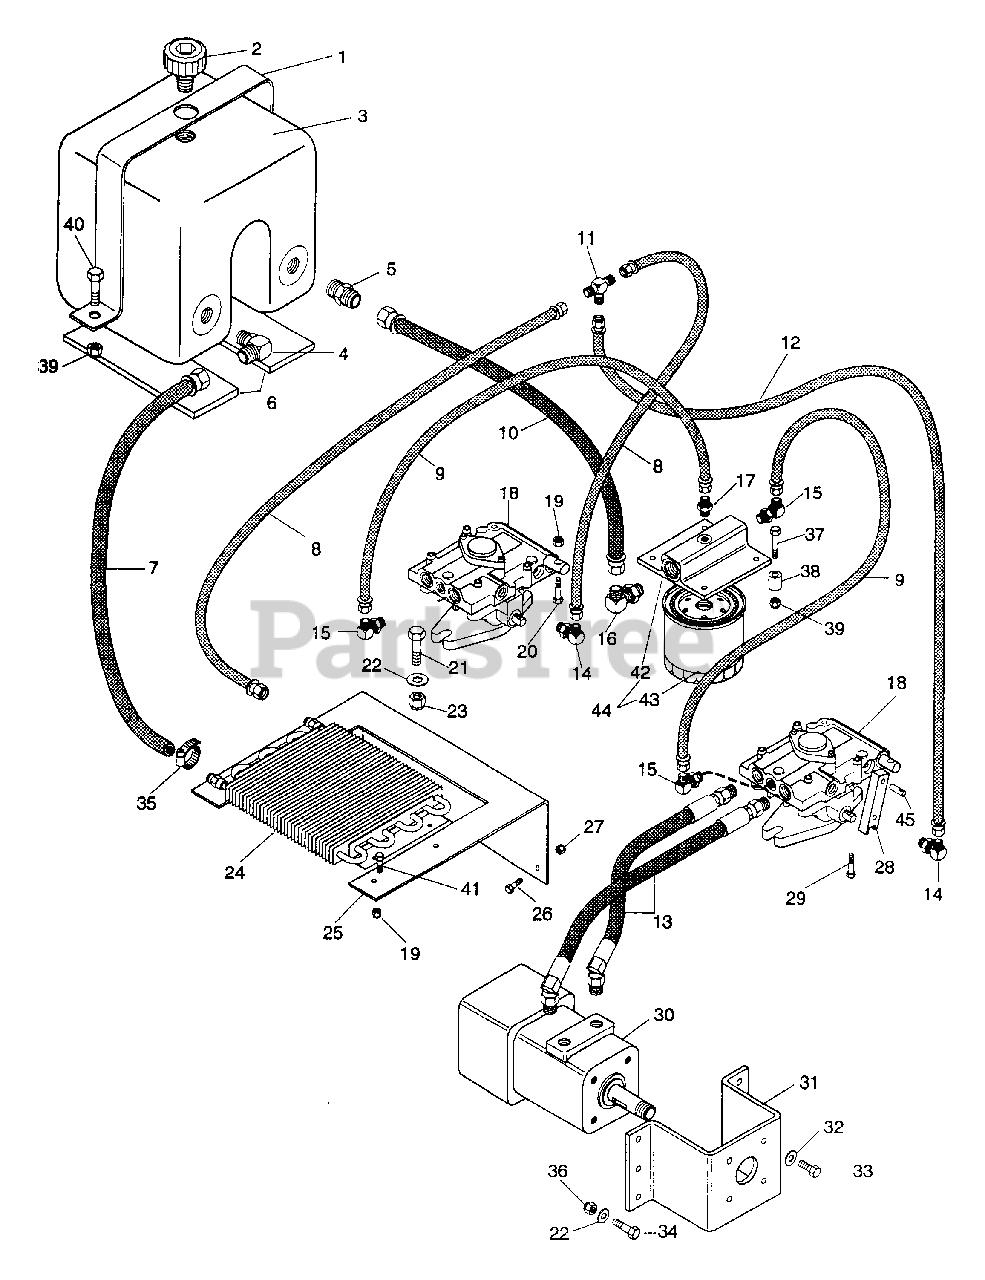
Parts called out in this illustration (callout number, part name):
1	Strap, Tank
2	Cap, Filter
3	Tank, Hydraulic
4	Adapter, .75 - .875
5	Adapter, Hydraulic
6	Pad, Gas Tank
7	Hose, Hydraulic Cooler to Tank (02,04)
7	Hose, Hydraulic Cooler to Tank (01,03)
8	Hose, Hydraulic Valve to Tank
9	Hose, Oil Filter to Pump
10	Hose, Hydraulic Tank to Filter
11	Adapter- Tee .56-18
12	Hose, Pump to Tee
13	Assembly, Hose Wheel Motor to Pump
14	Adapter, 2503-6-6
15	Adapter 2503-4-4
16	Adapter, Pipe .75-16 "O" Ring M37
17	Adapter 0503-4-4
18	Variable Displacement Pump
19	Nut, Lock Nylon .250-20
20	Bolt, Hex .25-20 x 2.00 Gr. 5
21	Bolt, Hex .38-16 x 1.125
22	Washer, Flat Steel .406 x .812 x .065
23	Nut, Lock Cotter .375-16 Type N
24	Cooler, Oil
25	Bracket, Oil cooler Kohler (02, 04)
25	Bracket, Oil Coller B&S (01,03)
26	Bolt, Hex .38-16 x 1.125
27	Nut, Lock Nylon .375-16
28	Arm Pump Actuating
29	Screw, Cap 10-24 x .75 Hex
30	Motor, Hydralic Wheel
31	Bracket, Wheel Motor
32	Washer, Lock .375 x .094 Medium
33	Bolt, Hex .380-16 x .875
34	Bolt, Hex .38-16 x 1.00 Gr. 5
35	Clamp, .88 Diameter Hose
36	Nut, Lock Nylon .375-16
37	Bolt, Hex .31-18 x 2.00 Gr. 5
38	Bushing, Steel .328 x .462 x 1.00
39	Nut, Lock Nylon .312-18
40	Bolt, Hex .31-18 x .75 Gr. 5
41	Bolt, Hex .25-20 x .63
42	Assembly, Head
43	Element
44	Assembly, Spin-on Lube
45	Pin, Dowel
